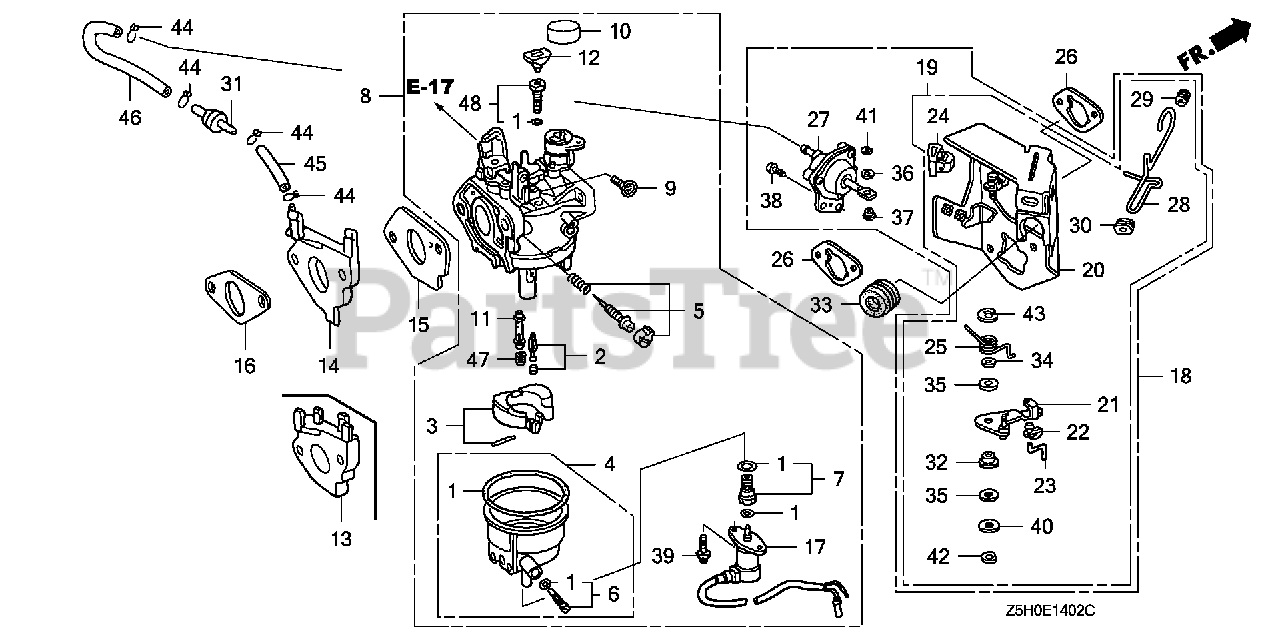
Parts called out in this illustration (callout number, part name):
1	GASKET SET
2	VALVE SET, FLOAT
4	CHAMBER SET, FLOAT
6	SCREW SET, DRAIN
8	CARBURETOR ASSY. (BE21G C)
9	SCREW, THROTTLE STOP
10	CAP, CHOKE DUST
11	NOZZLE, MAIN
12	COLLAR, SETTING
14	INSULATOR, CARBURETOR
15	GASKET, CARBURETOR
16	GASKET, INSULATOR
17	VALVE ASSY., SOLENOID
18	STAY ASSY., MANUAL CHOKE
20	STAY, SOLENOID
21	LEVER, CHOKE
22	JOINT, ROD
23	ROD, CHOKE
24	STOPPER, CHOKE ROD
25	SPRING, MANUAL CHOKE
26	GASKET, AIR CLEANER
27	DIAPHRAGM ASSY.
28	ROD, CHOKE CONTROL
29	GROMMET, CHOKE ROD
30	GUIDE, CHOKE ROD
31	VALVE, DASHPOT CHECK
32	BUSH, ARM PIVOT
33	GROMMET, FENDER
34	WASHER, CHOKE LEVER
35	SEAL, CHOKE LEVER
36	WASHER, THRUST (2.7X8)
37	COLLAR, LEVER
38	SCREW, PAN (5X12)
39	SCREW-WASHER (5X12)
40	WASHER, PLAIN (5MM)
41	E-RING (2MM)
42	E-RING (4MM)
43	E-RING (7MM)
44	CLIP, TUBE (B7)
45	BULK HOSE, VACUUM (3.5X8000) (3.5X55)
46	BULK HOSE, VACUUM (3.5X8000) (3.5X75)
47	JET, MAIN (#88)
47	JET, MAIN (#90)
47	JET, MAIN (#92)
48	JET SET, PILOT (#40)
